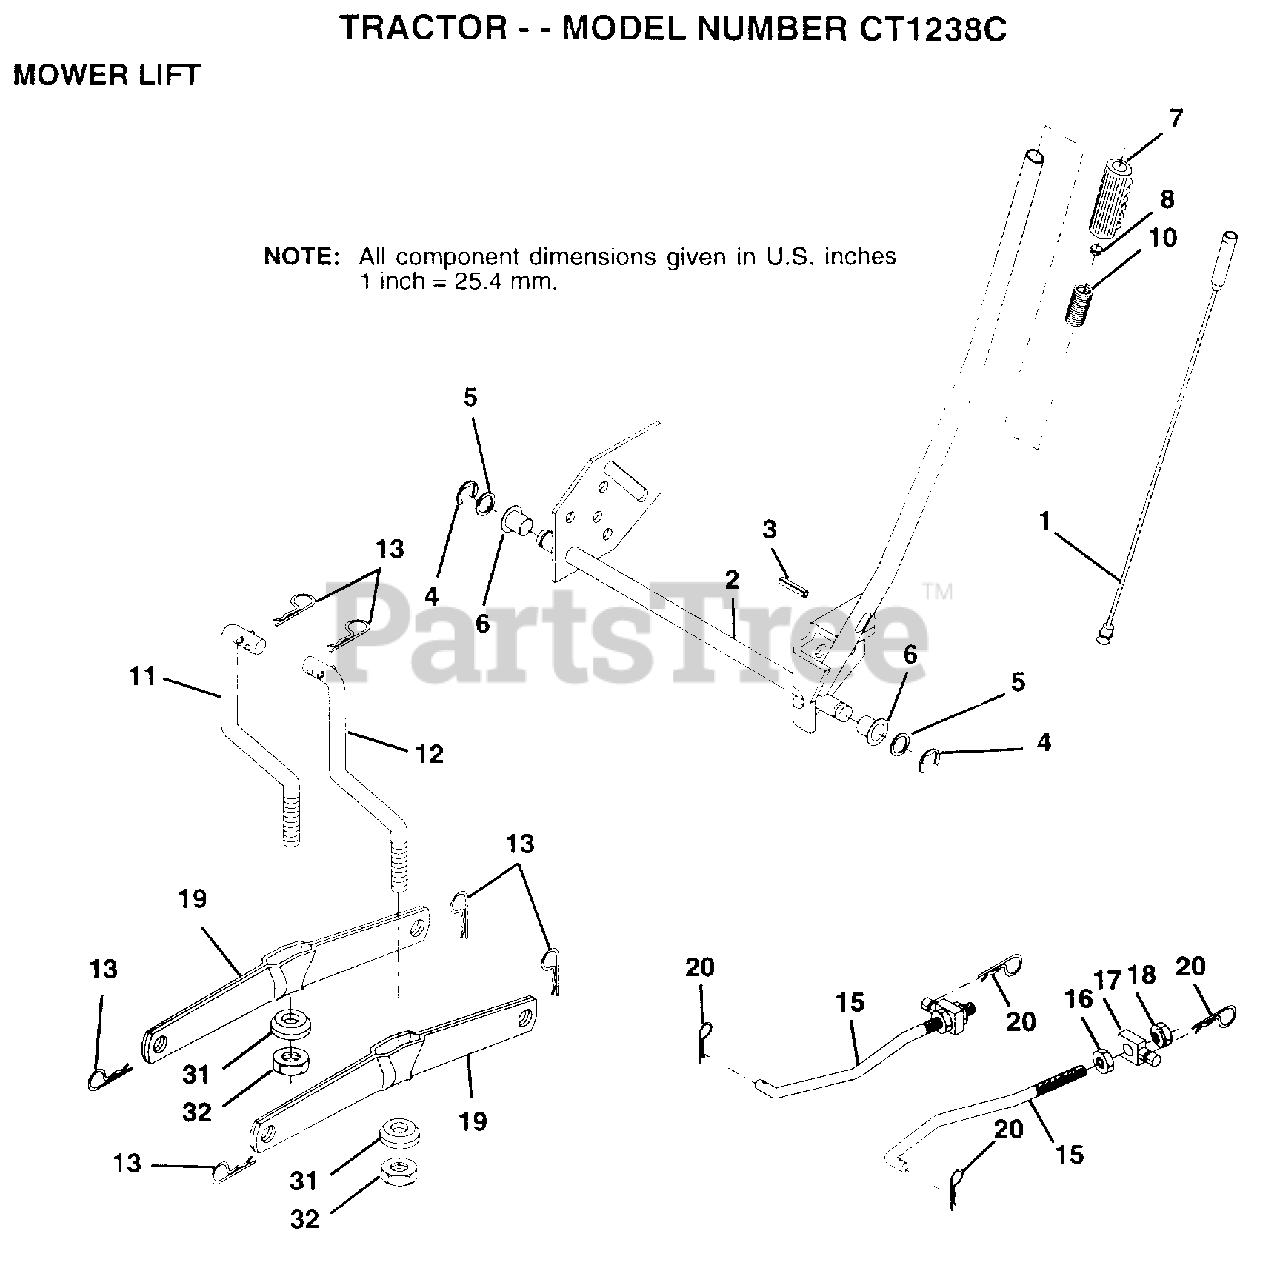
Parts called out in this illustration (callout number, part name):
1	WIRE ASM
3	PIN-GROOVE LT
5	WASHER
6	NYLON BEARING
7	GRIP
15	LINK.FRONT
16	NUT
17	TRUNION
18	NUT.LK.W/WSH.1/2.
19	ARM SUSP REAR
20	RETAINER.SPRING
31	BEARING PVT LH
32	NUT.CROWNLOCK.3/8
